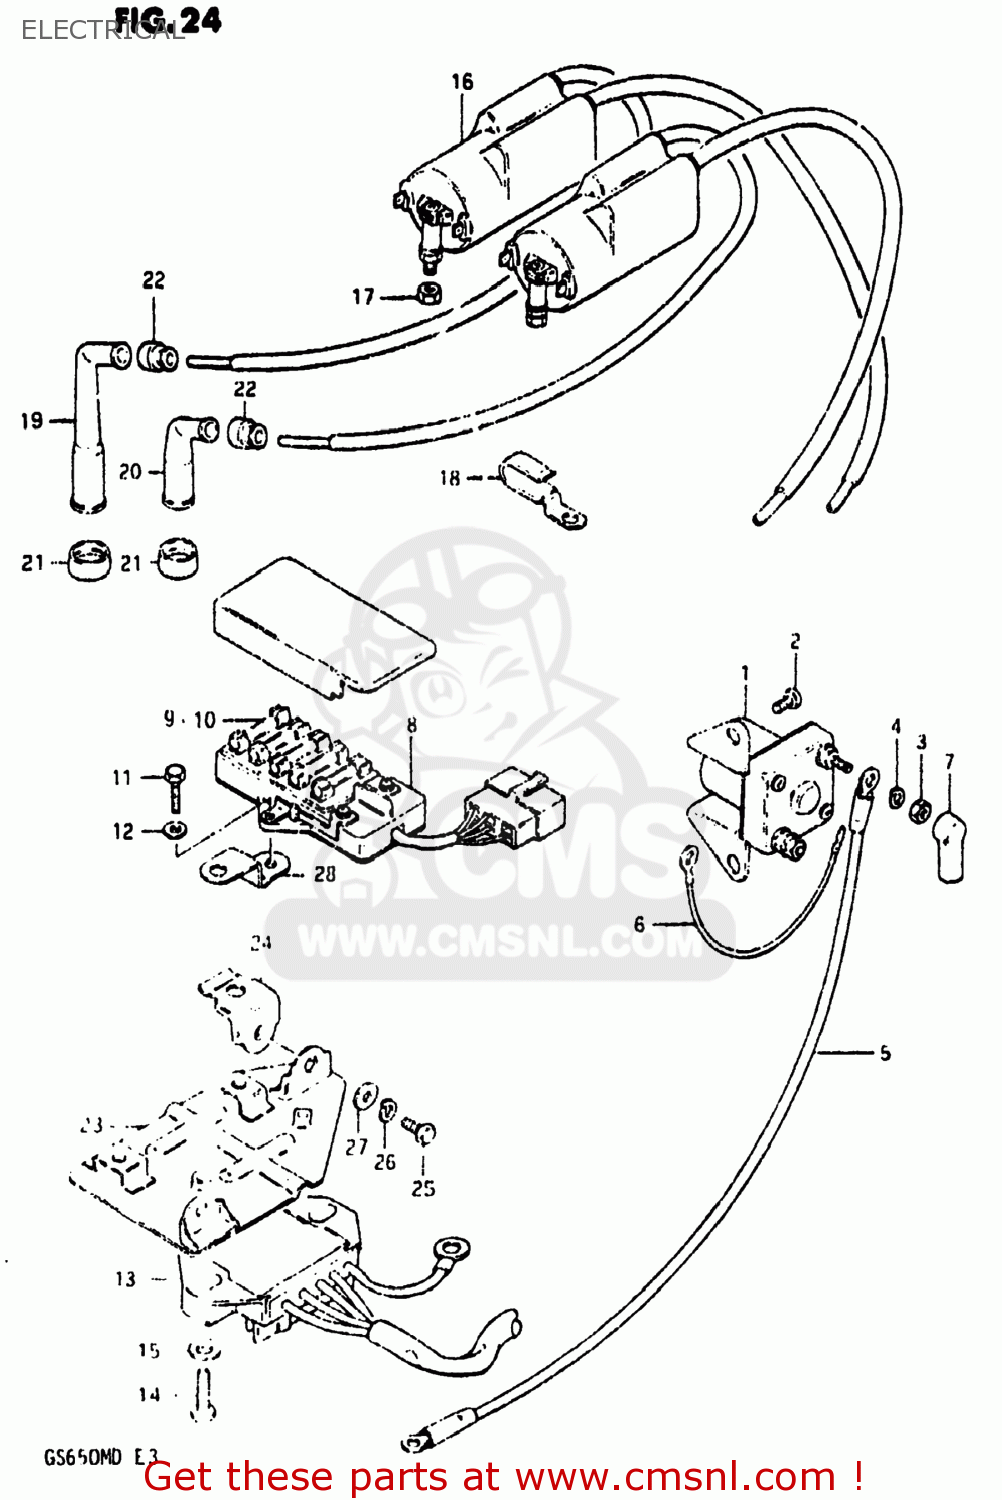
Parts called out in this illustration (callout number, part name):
1	RELAY ASSY,STARTING MOTOR
2	SCREW
3	NUT 6MM
4	LOCK WASHER
5	CABLE,STARTING MOTOR
6	LEAD WIRE
7	CAP,STARTER RELAY
8	BOX ASSEMBLY,FUSE
9	FUSE(15A)
10	FUSE(15A)
11	BOLT, UPPER
12	WASHER
13	RECTIFIER ASSEMBLY
14	SCREW
15	WASHER
16	COIL ASSEMBLY,IGNITION
17	NUT
18	CLAMP
19	CAP ASSY,SPARK PLUG
20	CAP,SPARK PLUG
21	SEAL,SPARK PLUG
22	SEAL,SPARK PLU
23	PLATE,ELECTRIC PARTS H
24	BRACKET, PARTS HOLDER
25	BOLT
26	LOCK WASHER
27	WASHER
28	BRACKET
